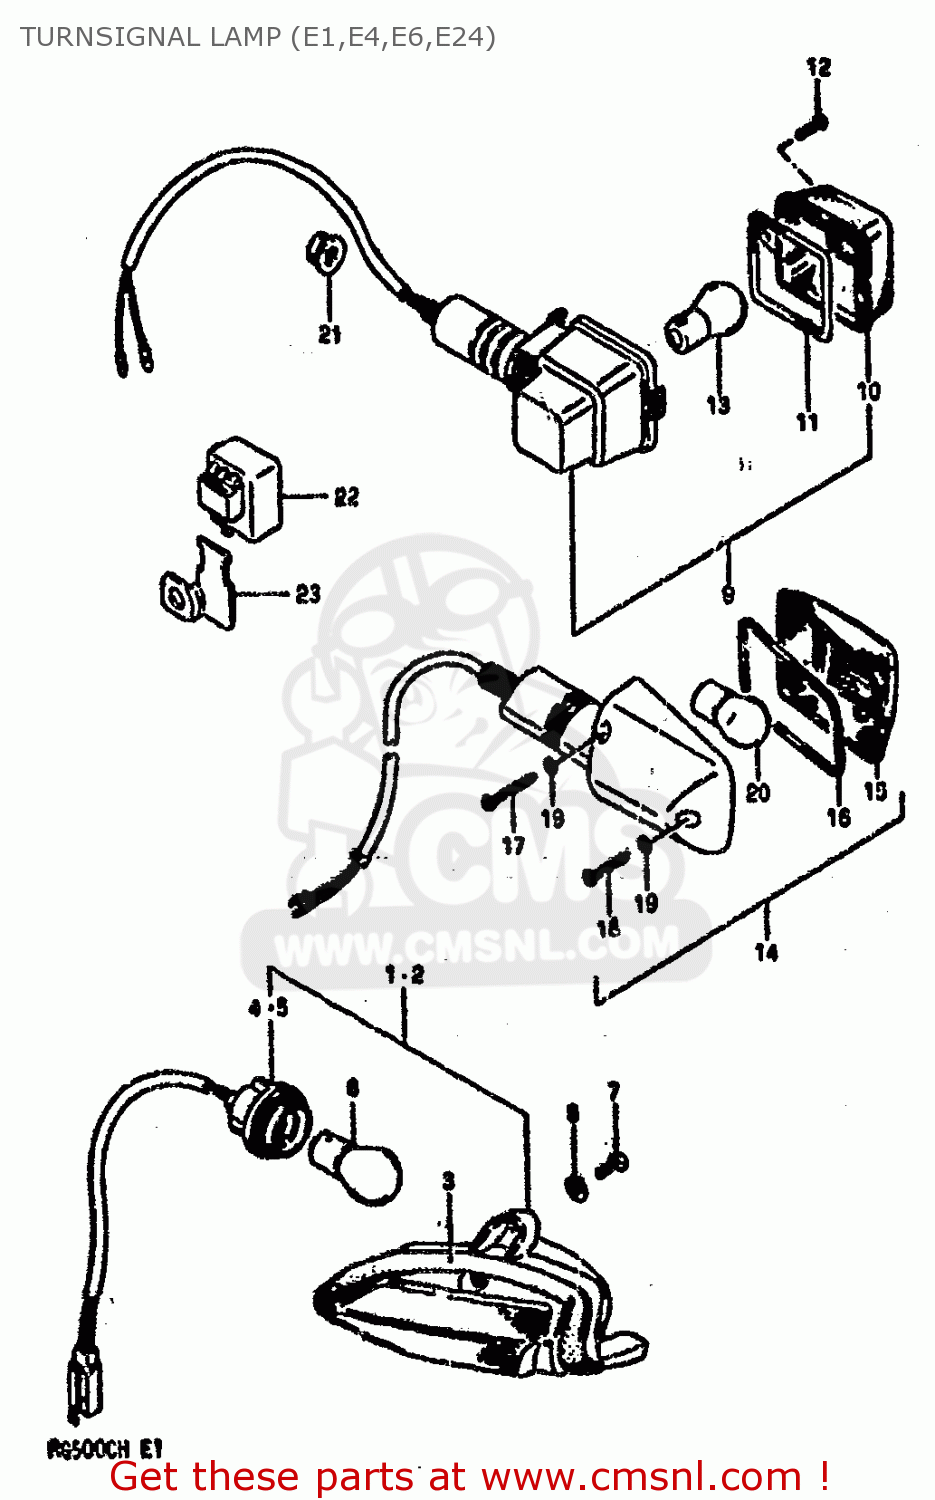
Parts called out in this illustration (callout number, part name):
1	LAMP,FRONT TURNSIGNAL RH
2	LAMP,FRONT TURNSIGNAL LH
3	GASKET
4	SOCKET,RH
5	SOCKET,LH
6	BULB 12V 21W
7	SCREW
8	WASHER
9	LAMP,REAR TURNSIGNAL
10	LENS
11	GASKET (NAS)
12	SCREW
13	BULB 12V 21W
14	LAMP ASSY,RR TURNSIGNAL
15	LENS
16	GASKET (NAS)
17	SCREW(3X30)
18	SCREW
19	GASKET (NAS)
20	BULB(12V23W,STANLEY,A4577A)
21	NUT
22	RELAY ASSEMBLY,TURN SIGNAL
23	BRACKET,TURN SIGNAL RELAY
